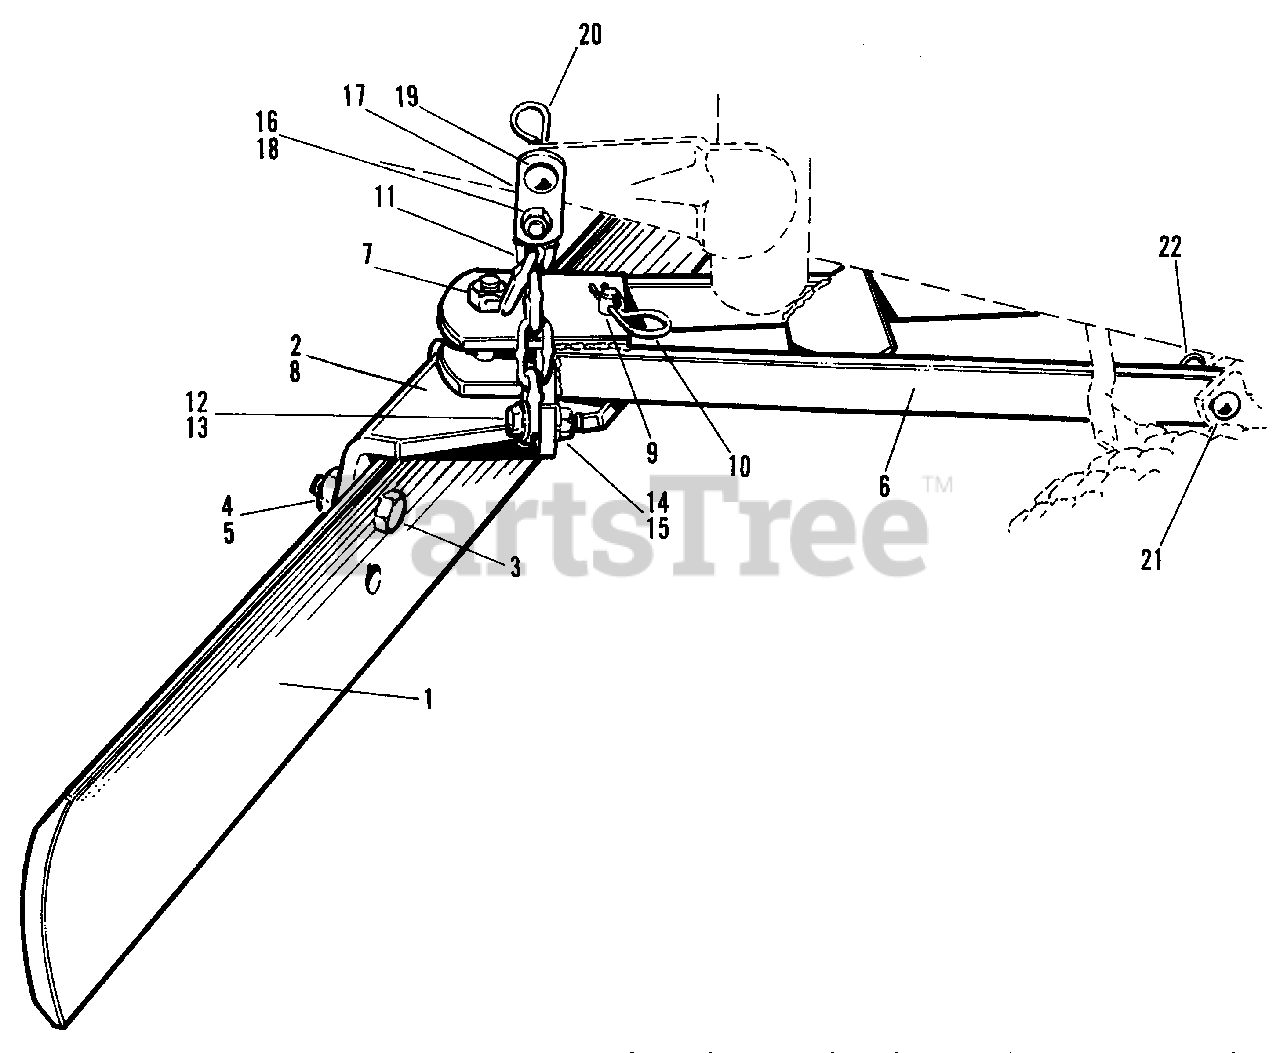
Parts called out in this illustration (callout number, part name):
1	40" Grader Blade
3	Hex Capscrew, 5/8"-11 x 2" lg.
4	Lock Washer, 5/8"
5	Hex Nut, Full, 5/8"-11
6	Pull Bar Assembly
7	Hex Capscrew, 5/8"-11 x 3" lg.
8	Hex Nut, Full Lock, 5/8"-11
10	Spring Clip
11	Chain
12	Hex Capscrew, 3/8"-16 x 1-1/4" lg.
13	Plain Washer, 3/8"
14	Lock Washer, 3/8"
15	Hex Nut, Full, 3/8"-16
16	Hex Capscrew, 3/8"-16 x 1" lg.
18	Hex Nut, Full, Lock, 3/8"-16
20	Spring Clip
22	Spring Clip
